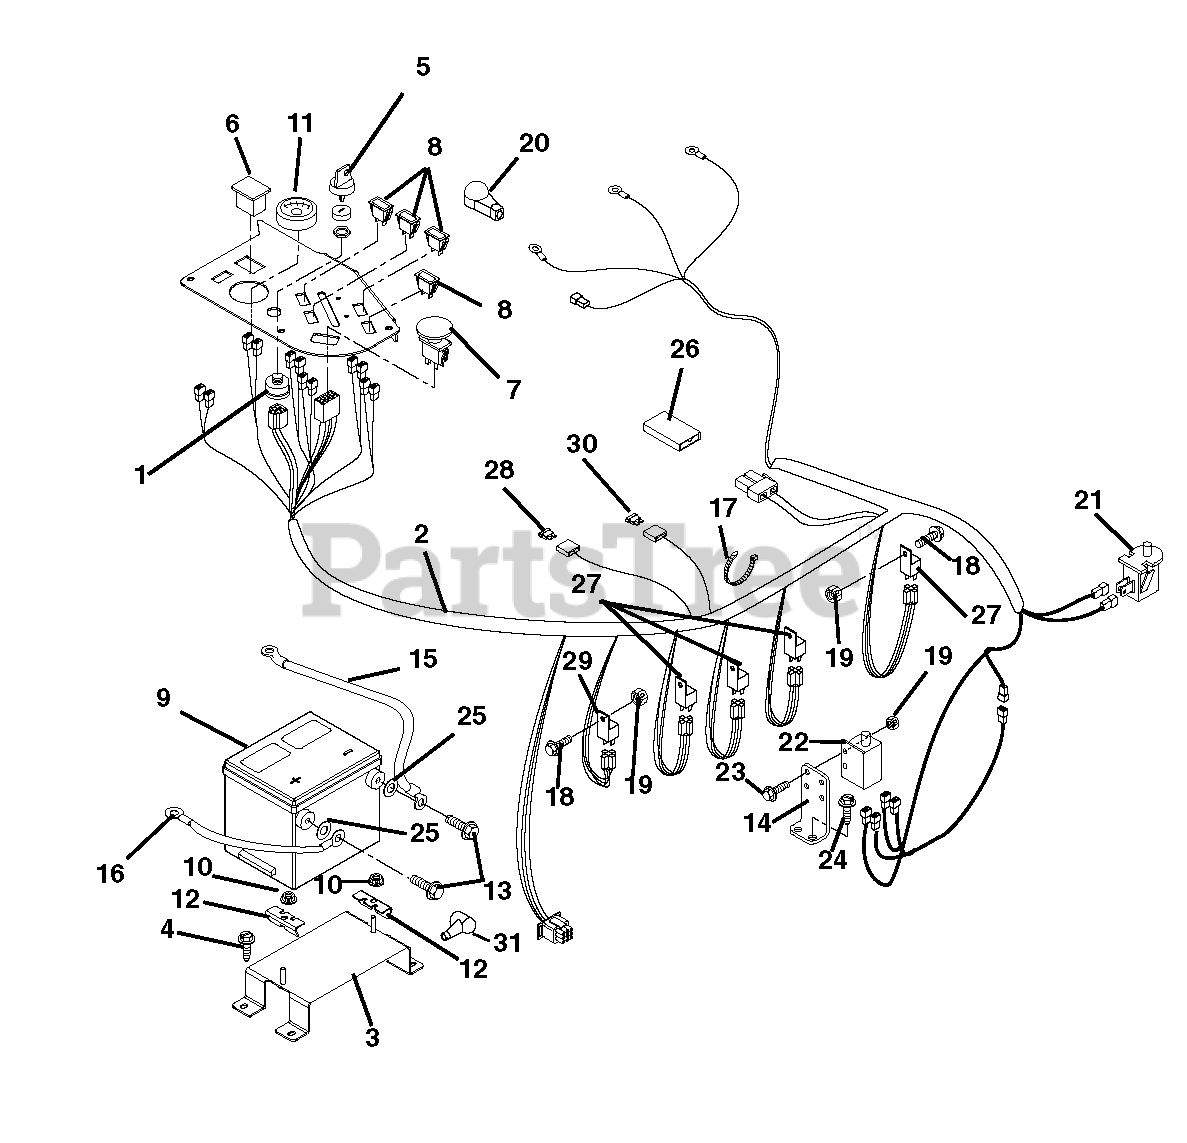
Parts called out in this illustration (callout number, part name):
1	Switch, Ignition
2	Harness, Wiring
3	Weldment, Battery Support
4	Screw, Tapping .38-16 x .75 Hex Washer Head
5	Key, with Cap
6	Hour Meter w/ Maintenance
7	Switch, Clutch With Retainer Ring
8	Light, Indicator
9	Battery with Tube
10	Nut, Locking Top Flange .31-18
11	Gauge, Temperature
12	Bracket, Battery Hold-Down
13	Bolt, Hex .25-20 x .75 Grade 5
14	Mount, Safety Switch
15	Cable, Positive Battery with Boots
16	Cable, Negative Battery
17	Cable Tie
18	Screw, Machine 10-24 x .75 Hex Washer Head
19	Nut, Locking Nylon 10-24 With Insert
20	Boot Terminal, Red
21	Switch, Snap Mounting (N.O.) (Included with Seat)
22	Switch, Single Pole
23	Screw, Machine 10-24 x .75 Hex Washer Head
24	Screw, Tapping .25-20 x .50 Hex Washer Head
25	Washer, Flat-Steel .406 x 1.00 x ..083
26	Diode, Connector Shell
27	Relay (Included with Harness)
28	Fuse, ATO 30 Amp (Included with Harness)
29	Pre-Heat Timer (Included with Engine)
30	Fuse, ATO 60 Amp (Included with Harness)
31	Battery Terminal Boot, Red
